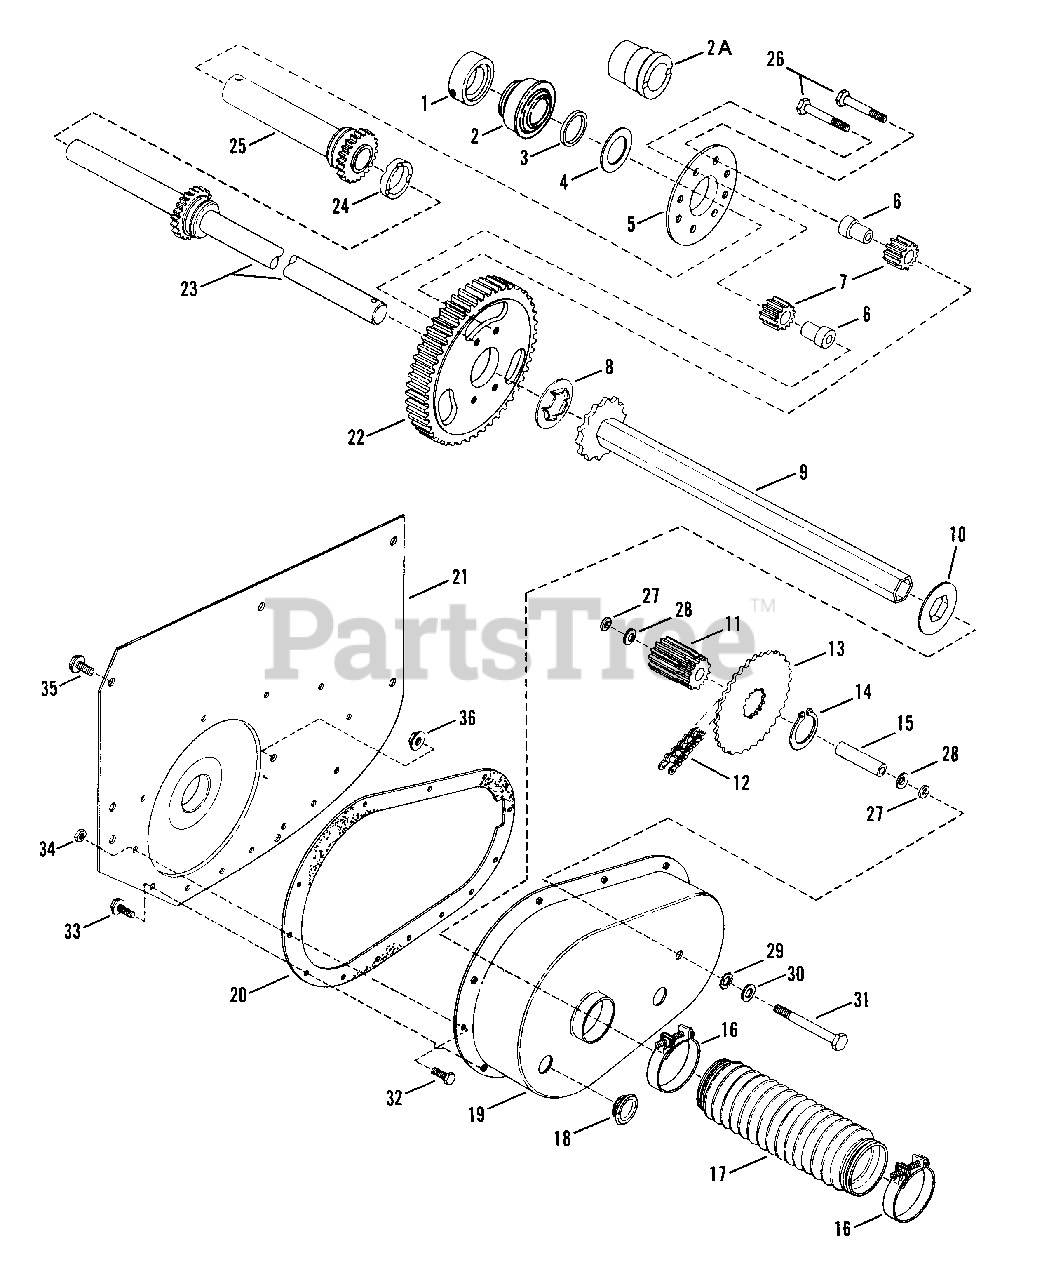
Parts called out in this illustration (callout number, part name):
1	COLLAR, Lock
2	BALL BEARING, Axle, Right Hand Fender
2A	BEARING, Axle, Right Hand Fender
3	SPACER, Short Axle
4	WASHER, Thrust
5	PLATE, Differential
6	SPACER, Pinion
7	PINION GEARS, Differential
8	WASHER, Thrust
9	ASSEMBLY, Drive Hex Tube
10	WASHER, Hex Insert
11	GEAR, 11 Teeth, 10 Pitch
12	CHAIN, 46 Pitch (#35)
13	SPROCKET
14	RING, Retaining
15	SPACER
16	CLAMP, Boot 1.875"
17	BOOT, Oil Seal
18	PLUG, Oil Fill & Check
19	CASE, Transmission
20	GASKET, Transmission Case
21	FENDER, Right Hand (2.498" ID Hole)
21	FENDER, Right Hand (1.62" ID Hole)
22	GEAR, 63 Teeth, 10 Pitch
23	AXLE, Long
24	SPACER, Differential (1.25" ID x .425 Wide)
25	AXLE, Short
26	CAPSCREW, 5/16 - 24 x 1-5/8" Hex, Special Lock
27	O-RING, 5/16"
28	WASHER, Belleville
29	WASHER, 5/16 External Tooth Lock
30	WASHER, 5/16 Flat
31	BOLT, 5/16 - 24 x 2-5/8" Idler
32	SCREW, 1/4 - 20 x 5/8" Hex Head Cap
33	SCREW, 1/4 - 20 x 5/8", Self-Tapping
34	NUT, 1/4 - 20 Hex Lock
35	SCREW, 5/16 - 18 x 5/8", Self-Tapping
36	NUT, 5/16 - 24 Hex Flange Lock
